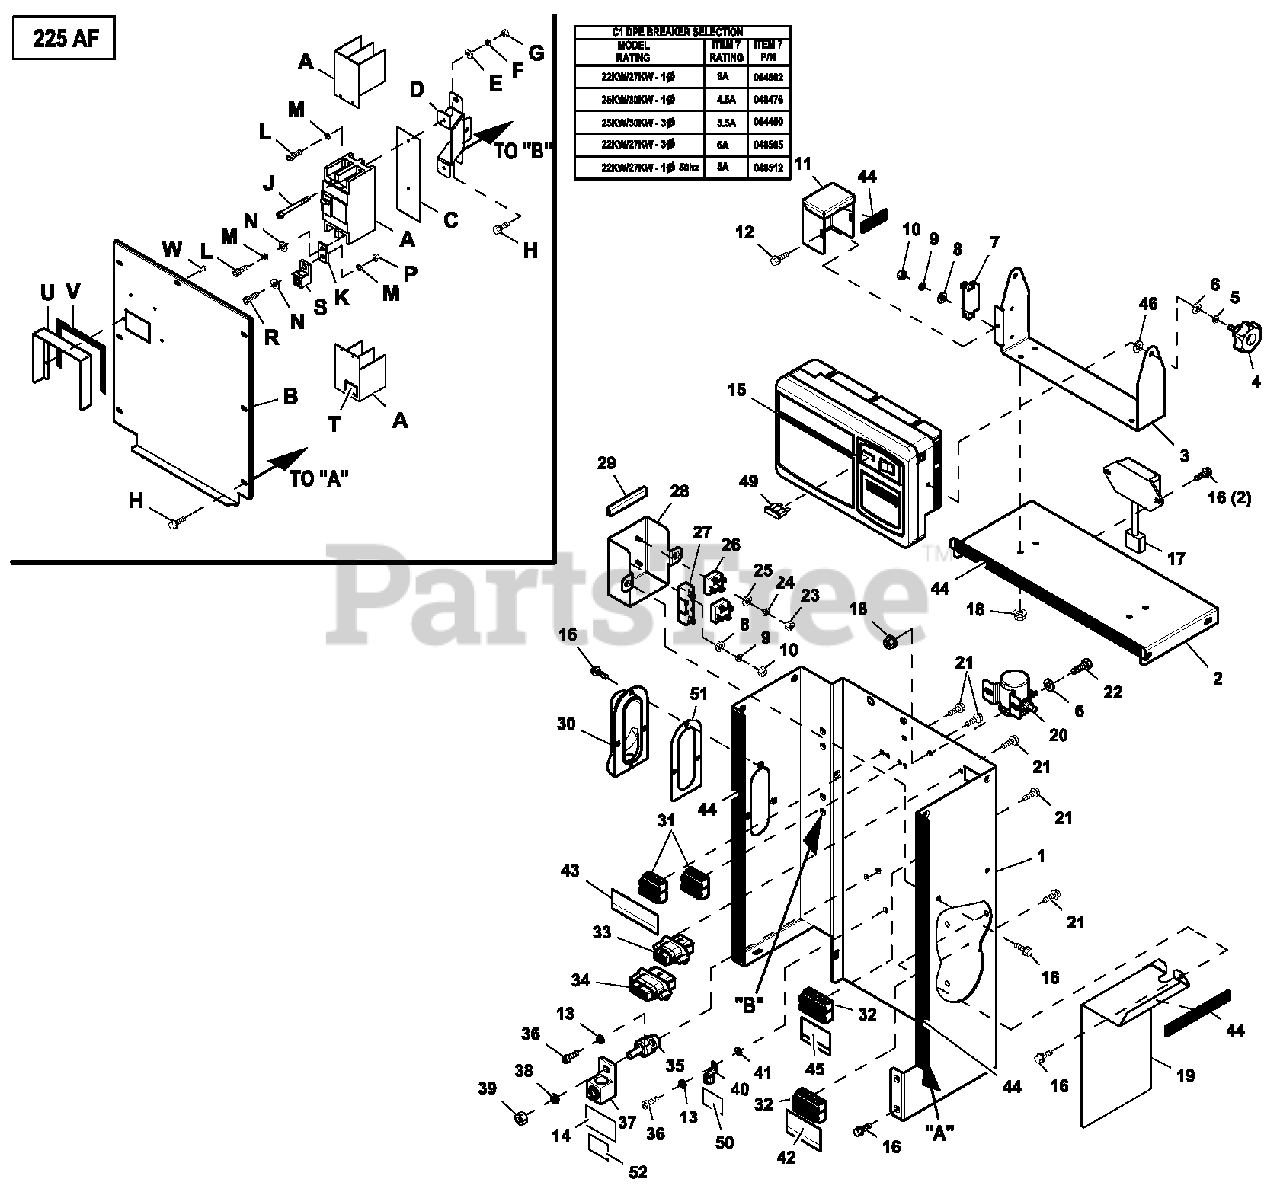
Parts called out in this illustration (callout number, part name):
1	CONBOX BACK/SIDES C1 CPL
2	CONBOXTOP C1 CPL
3	BRACKET GIMBAL CONTROL PNL RAW
4	KNOB M6-1.0 CONTROL PANEL
5	WASHER LOCK M6-1/4
6	WASHER FLAT 1/4-M6 ZINC
7	CIRCUIT BREAKER
8	WASHER FLAT M3
9	WASHER LOCK M3
10	NUT HEX M3-0.5 G8 CLEAR ZINC
11	COVER DPE BREAKER NEXUS
12	SCREW HHTT M4-0.7 X 8 ZP
13	WASHER LOCK#8-M4
14	DECAL NEUTRAL
15	ASSY CTRL PROGRAMMED
16	SCREW HWHT M6-1 X 16 N WA Z/JS
17	REGULATOR-DC ALT
18	NUT FLANGE M6-1.0 NYLOK
19	SHIELD HIGH/LOW C1 RAW
20	RELAY SOLENOID 12VDC PNL MNT
21	SCREW HHSP #10 X 3/8 HI-LOW
22	SCREW HHC M6-1.0 X 20 C8.8
23	NUT HEX M5-0.8 G8 CLEAR ZINC
24	WASHER LOCK M5
25	WASHER FLAT M5
26	DIODE BRIDGE 1P 35A 1000V
27	RES WW 15R 5% 25W QK CONN
28	COVER VOLTAGE SHIELD
29	TRIM VINYL BLACK 1/8GP (3"LG)
30	COVER BELL HOUSING CONBOX
31	TERM BLOCK 3P UL 12-20AWG
32	TERM BLOCK 4P UL 12-20AWG
33	MX150L SLRRMNT 22-18 8P W/O GA
34	MX150L SLRRMNT 22-18 12P W/OGA
35	JUNCTION BLOCK 3/8-16
36	SCREW PHTT M4-0.7 X 12 ZP
37	LUG SLDLSS 350-#6X13/32 AL/CU
38	WASHER LOCK 3/8
39	NUT HEX 3/8-16 STEEL
40	LUG SLDLSS #6-14 X 13/64 CU
41	WASHER LOCK EXT #10 STL
42	DECAL CUSTOMER CONTROL CONNECT
43	DECAL CONBOX TB1 CONNECTIONS
44	TAPE ELEC 1/2 FOAM (62" LG)
45	DECAL CUSTOMER POWER CONNECT
46	WASHER NYLON .257
49	FUSE ATO TYPE 7.5AMP (BROWN)
50	DECAL GROUND LUG
51	GASKET WIRE ENTRY COVER
52	DECAL CAUTION ELEC SHOCK SM
A	CB 150A 2 POLE 240V 225AF
B	COVER CB G 225AF C1 CONBOX
C	INSULATOR CB 2P 225AF
D	SPRT CIRCUIT BREAKER G 225AF
E	WASHER FLAT #8 ZINC
F	WASHER LOCK#8-M4
G	NUT HEX #8-32 STEEL
H	SCREW HWHT M6-1 X 16 N WA Z/JS
J	SCREW RHM #8-32X3-1/4
K	BUS BAR 200A LUG ADAPTOR
L	SCREW SHC M8-1.25 X 20 G8
M	WASHER LOCK M8-5/16
N	WASHER FLAT 5/16-M8 ZINC
P	NUT HEX M8-1. 25 G8 CLEAR ZINC
R	SCREW SHC M8-1.25 X 25 C12 . 9
S	LUG SLDLSS 300 MCM-6 AL/CU
T	DECAL TERMINAL SHOCK HZD BI
U	SHIELD CB HANDLE CONBOX
V	TAPE ELEC 1/2 FOAM
W	RIVET POP . 125 X .275 SS
